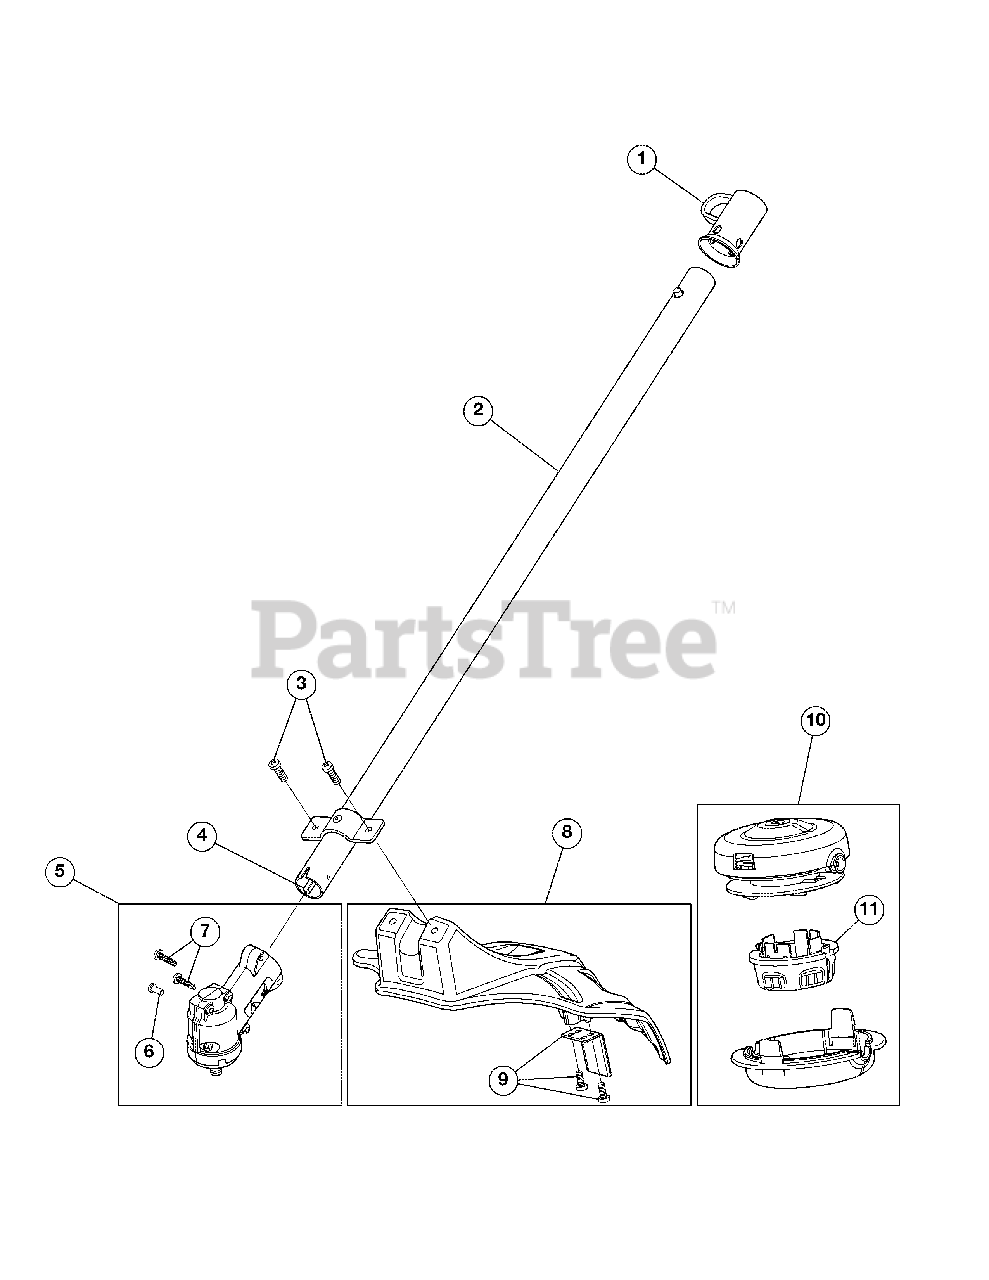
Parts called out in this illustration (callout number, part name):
2	Lower Drive Shaft Housing
3	Shield Mounting Screws
4	Lower Flexible Drive Shaft
5	Gearbox Assembly (Incl. 6 and 7)
6	Anti-Rotation Screw
7	Gearbox Mounting Hardware
8	Shield Assembly (Incl. 9)
9	Blade Assembly
10	Cutting Head Assembly (Incl. 11)
11	Bump Knob
